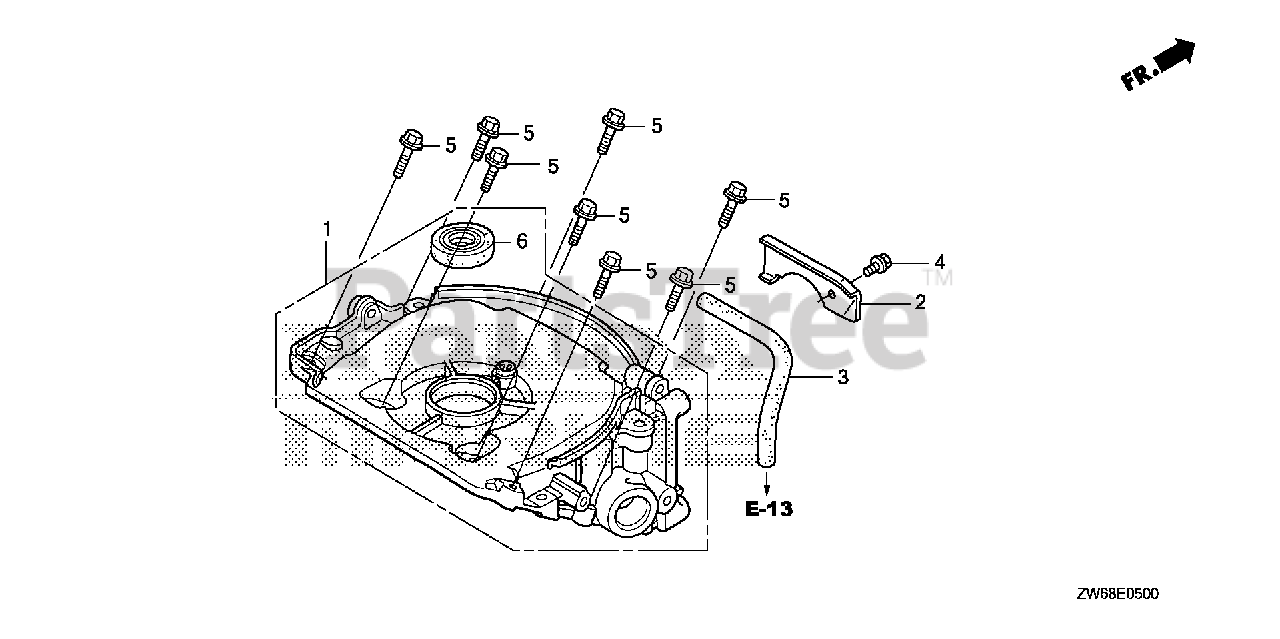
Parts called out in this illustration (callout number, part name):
1	CASE ASSY., OIL
2	PLATE, TUBE SETTING
3	TUBE, CLUTCH HOUSING BREATHER
4	BOLT, FLANGE (5X10) (CT200)
5	BOLT, FLANGE (5X23) (CT200)
6	OIL SEAL (17X27X5) (KOYO)
